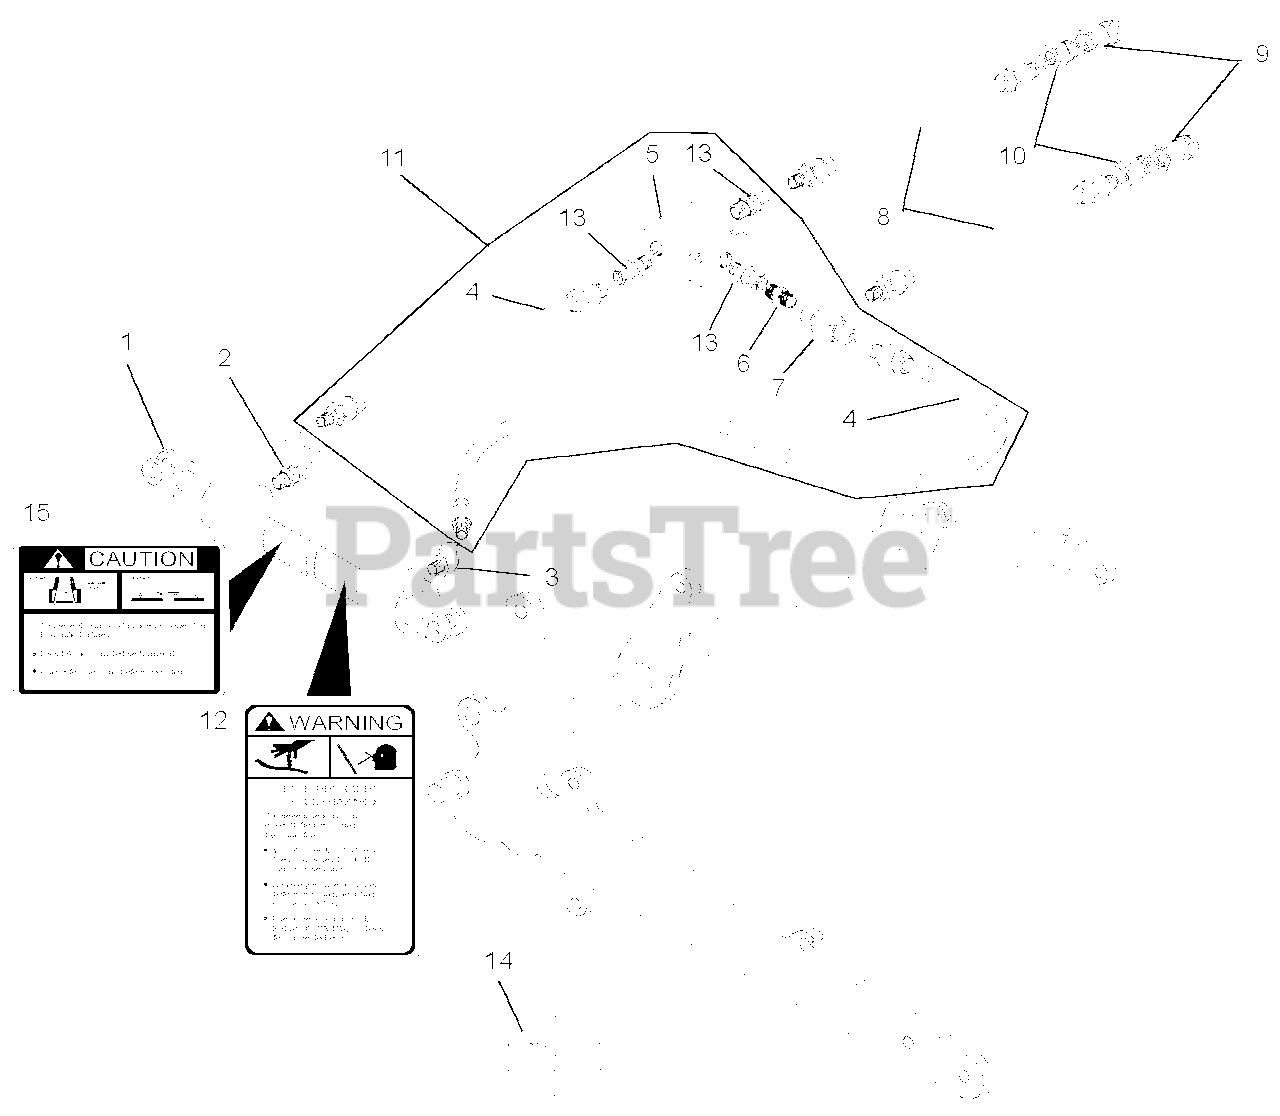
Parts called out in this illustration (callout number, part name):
1	Cylinder, Hydraulic
2	Adapter .25 FNPT x .25 MNPT
3	Adapter .25 FNPT x .25 MNPT
4	Adapter .25 FNPT x .25 MNPT 45-Degree
5	Check Valve
6	Nipple .25 MNPT
7	Tee .25 FNPT
8	Hose Assembly, 120-Inch
9	Coupler, .50 FNPT QD Male
10	Adapter, .50 MNPT x .25 FNPT
11	Check Valve Assembly (Includes Items 4, 5, 6, 7, and 13)
12	Decal, Caution
13	Adapter .25 FNPT x 6 ORB
14	Seal Kit (for 07001007 Hydraulic Cylinder)
15	Decal, Warning
